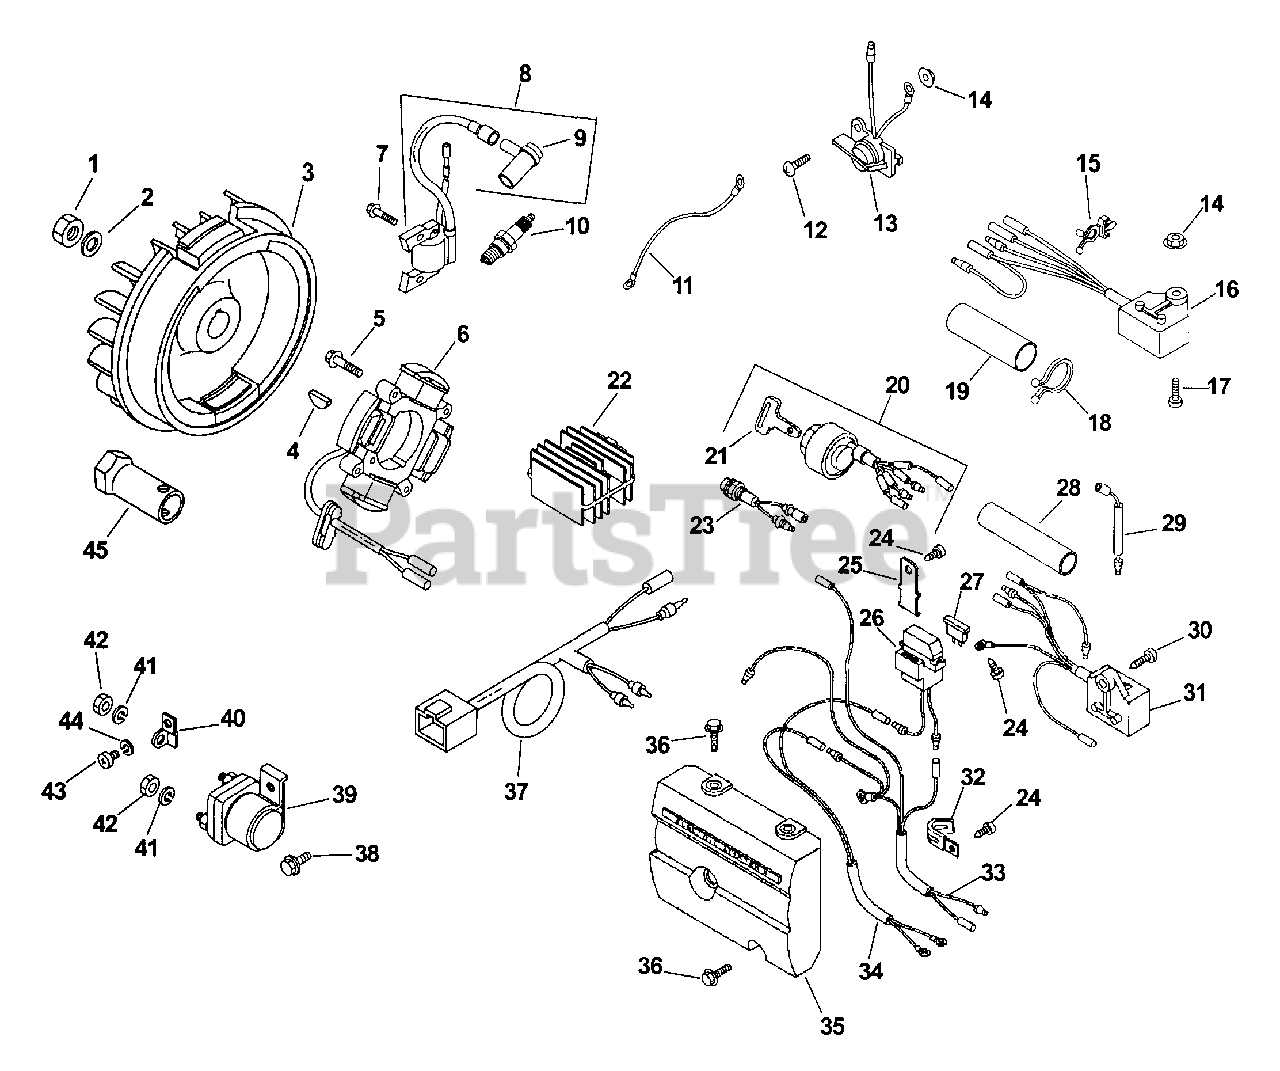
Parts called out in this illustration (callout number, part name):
1	NUT, FLYWHEEL
2	WASHER, F.W.
4	KEY, WOODRUFF
8	KIT, MOD & SP CAP(CS 4&6 CHINA)
9	CAP ASSEMBLY
10	SPARK PLUG
11	LEAD,KILL
12	SCREW, PAN HEAD
13	STOP SWITCH
14	NUT, STOP SWITCH
15	CLAMP, WIRE
